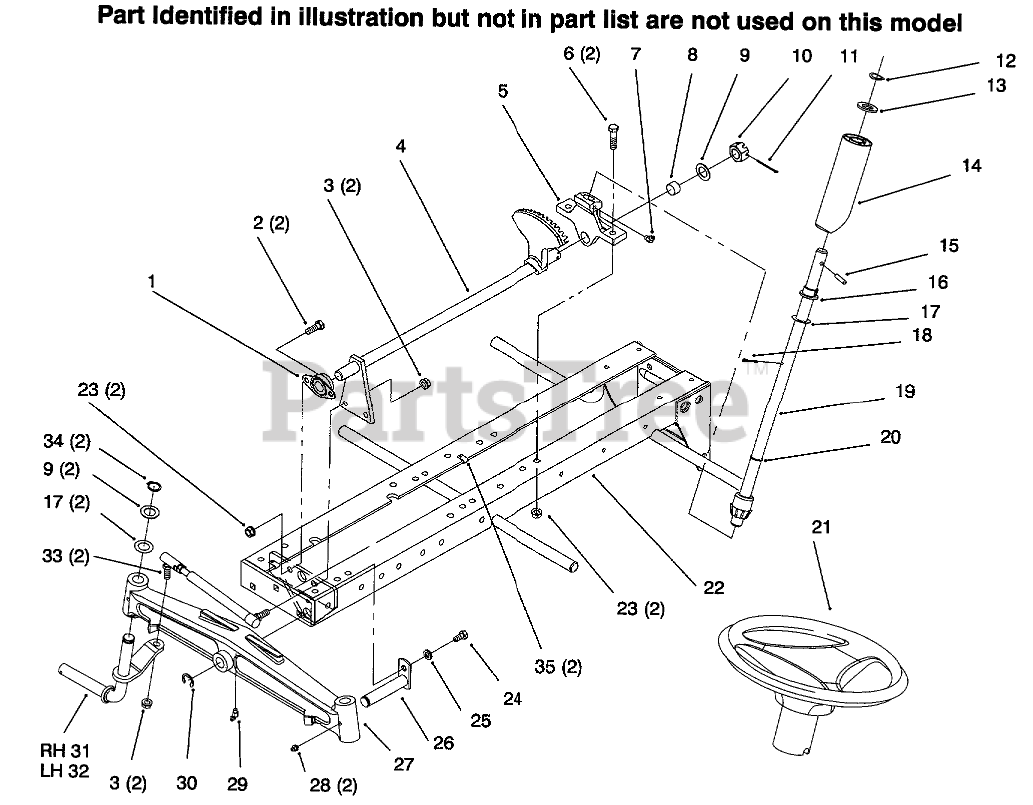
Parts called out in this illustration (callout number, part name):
1	BEARING-FLANGED
2	SCREW-HH
3	NUT-LOCK
4	Shaft
5	Support-Steering
6	SCREW-HH
7	FITTING-GREASE
8	BEARING-BRONZE
9	WASHER
10	NUT-HEX, SLOTTED
11	PIN-COTTER
12	WASHER-BOWED
13	WASHER-FLAT
14	TUBE-STEERING
15	PIN-ROLL
16	BEARING-FLANGED
17	PIN-COTTER
17	WASHER-SHIM
19	STEERING SHAFT ASM
20	O-RING
21	WHEEL - STEERING 15"
21:1	COVER-WHEEL
22	Frame
23	NUT-LOCK, NI
24	SCREW-HH
25	WASHER-LOCK
26	PIN AND PLATE ASM
27	AXLE-FRONT
28	FITTING-GREASE
30	E-RING
31	RH SPINDLE WA
32	LH SPINDLE ASM
33	ASM-Rod
34	RING-RETAINING
